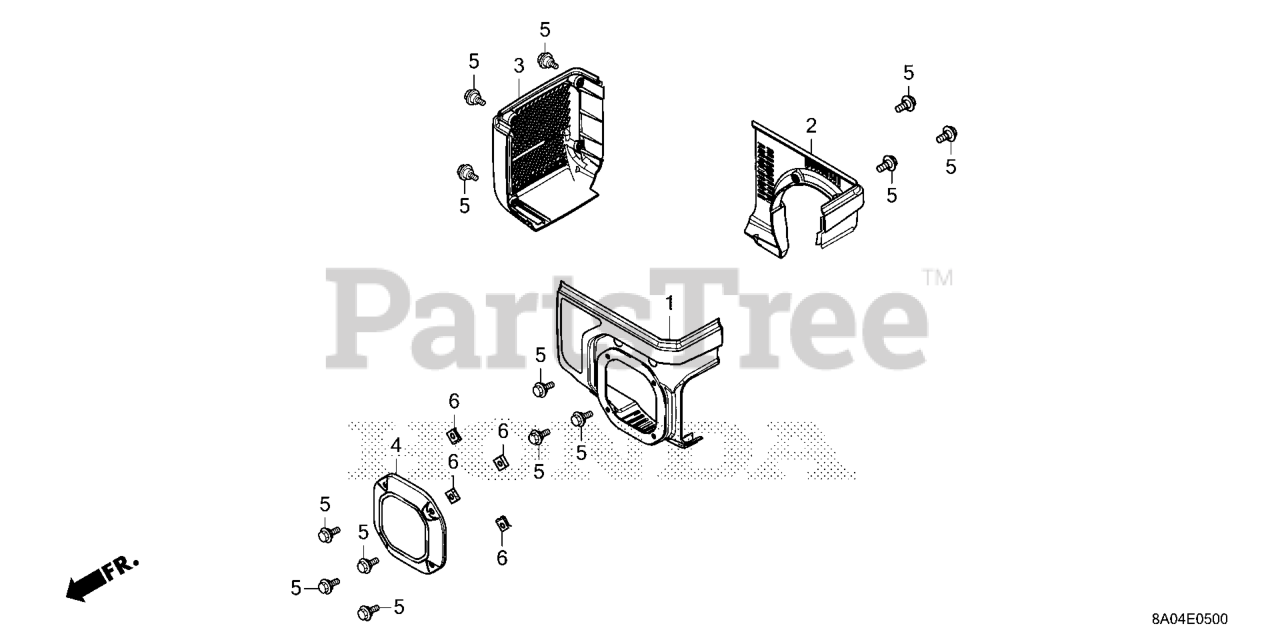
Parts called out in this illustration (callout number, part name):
1	COVER, FR. *NH1*
2	COVER, RR. *NH1*
3	COVER, PDU *NH1*
4	COVER, TOP *R280*
4	COVER, TOP *NH1*
5	BOLT, SPECIAL (6X12)
6	NUT, SPRING (6MM)
